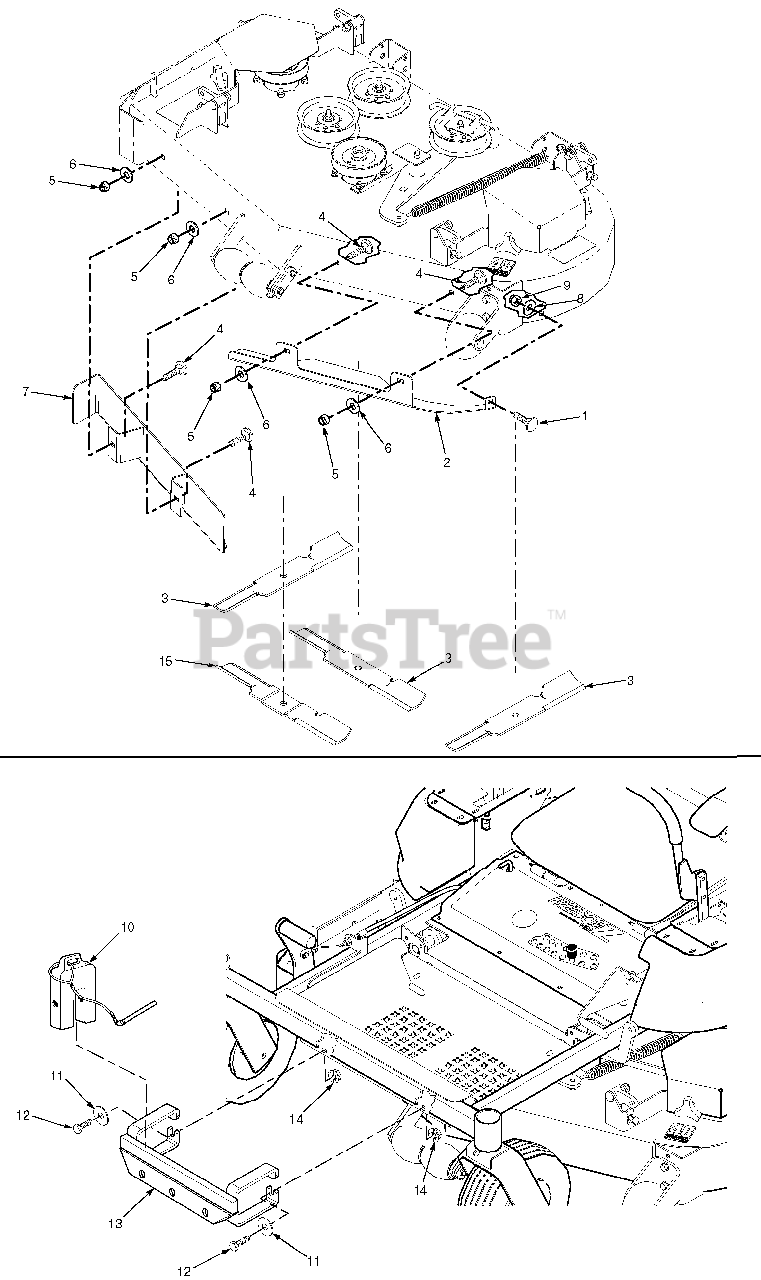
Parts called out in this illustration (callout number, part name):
1	Bolt, Carriage 5/16-18 x 3/4"
2	Baffle, LH
3	Cutter Blade, High Lift
4	Bolt, Carriage 3/8-16 x 1"
5	Nut, Elastic Stop 3/8-16
6	Flatwasher, 3/8-.438 x 1.00 x .083
7	Baffle Weldment, RH
8	Flatwasher, 5/16-.344 x .688 x .065
9	Nut, Center Lock 5/16-18
10	Weight Assembly (w/tether)
11	Flatwasher, 1/2-.562 x 1.375 x .109
12	Bolt, Hex Head 1/2-13 x 1-1/4"
13	Support Weldment, Weight Mounting
14	Nut, Serrated Flange 1/2-13
15	Cutter Blade, Cross
